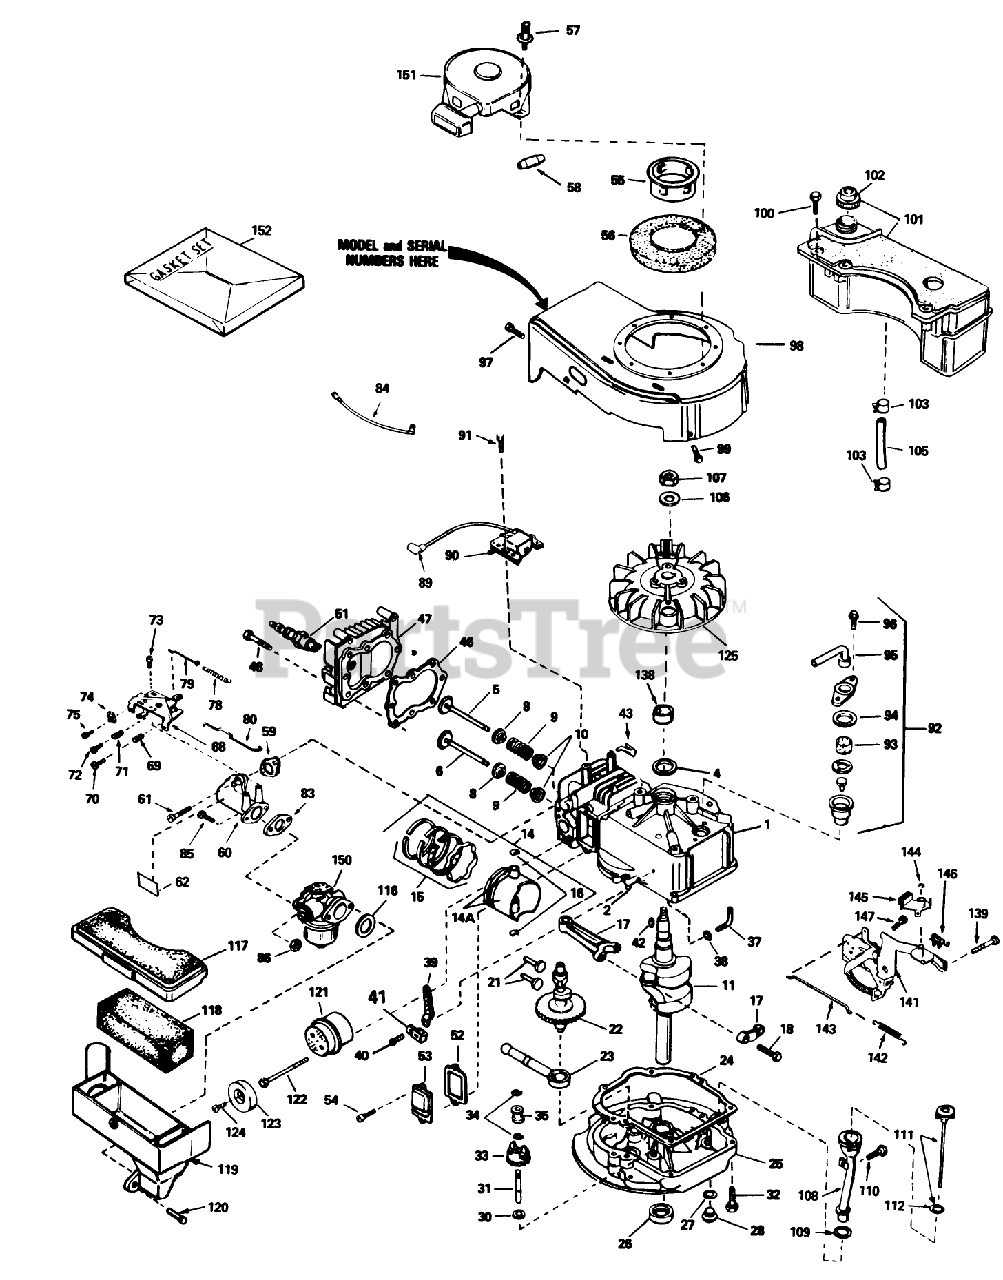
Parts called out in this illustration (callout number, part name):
1	Cylinder Assembly (Incl. Ref. #2, 4, 94 96)
2	Pin-Dowel
4	Seal-Oil
5	Valve, Intake (Std.) (Incl. Ref. #40)
5	Valve, Intake (1/32" oversize)(Incl. No. 40)
6	Valve, Exhaust (Std.)(Incl. No. 40)
6	Valve, Intake (1/32" oversize)(Incl. No. 40)
8	Cap-Upper Valve Spring
9	Spring-Valve
10	Cap-Valve, Spring
11	Crankshaft
14	Piston-Pin Ring Assy. (Std.)(Incl. Ref. #14A, 15 16)
14	Piston-Pin Ring Assy. (.010 oversize)(Incl. Ref. #14A, 15 16)
14	Piston-Pin Ring Assy. (.020 oversize)(Incl. Ref. #14A, 15 16)
14A	Piston Pin Assy. (Std)(Incl. Ref. #16)
14A	Piston Pin Assy. (.010 oversize) (Incl. Ref. #16)
14A	Piston Pin Assy. (.020 oversize) (Incl. Ref. #16)
15	Piston Ring Set Std.
15	Piston Ring Set .010 O.S.
15	Piston Ring Set .020 O.S.
16	Ring-Retaining, Piston Pin
17	Rod Assy., Connecting (Incl. Ref. #17)
18	Bolt-Rod, Connecting
21	Lifter-Valve
22	Camshaft(Mech.Comp. Release)
23	Oil Pump ASM
24	Gasket, Mounting
25	Flange Assy.-Mounting (Incl. Ref. #26, 27, 28 31)
26	Seal Oil
27	Gasket-Oil Drain
28	Plug Oil Drain
30	Washer-Flat
31	Shaft-Governor
32	Screw (1/4-20 x 1-1/4)
33	Governor Gear ASM
34	Ring-Retaining
35	Spool-Governor
37	Rod, Governor (Incl. No. 36)
38	Washer-Flat
39	Governor Lever
40	Screw
41	Clamp-Lever, Governor
42	Key-Flywheel
43	Clip-Wire
46	Gasket-Cylinder Head
47	2025A67 ADD.ASSEMBL
48	Screw (5/16-18x1-1/2)
51	Plug, Spark (Autolite 458, Champion J-19LM or equiv.)
52	Gasket-Breather
53	Cover-Valve
54	Screw
55	Cup-Starter
56	Screen-Starter
57	Pop Rivet (Can be purchased locally)
58	Retainer-Starter Rope
59	Gasket-Intake
60	Pipe-Intake (Incl. Ref. #59)
61	Screw (1/4-20 x 1)
62	Decal-Primer
68	Control Assy.-Remote Speed (Incl. Ref. #69 thru 72 76)
69	61709/GIL1515A/95-5
70	Screw
71	Spring-Compression
72	Screw
73	Screw (10-24 x 9/16)
74	Conduit
75	Screw (10-32 x 3/8)
78	Spring Governor
79	2035A67 ADD.ASSEMBL
80	Link-Throttle
83	Gasket
84	Ground Wire
86	Nut and Lock Washer (1/4-28)
89	Cover-Spark Plug
90	Solid State
91	Screw
92	Breather Assy. (Incl. Ref. #46 thru 51)
93	Element-Breather
94	Gasket-Breather
95	Tube, Breaker
96	Screw (10-24 x 9/16)
97	Screw (10-24 x 9/16)
98	Housing-Blower
99	Screw (1/4-20 x 1/2)
100	Screw (10-32 x 35/64)
101	Tank Assembly-Fuel (Incl. Ref. #102)
102	Cap-Fuel
103	Clamp-Line, Fuel
105	Line-Fuel
106	Washer-Belleville
107	Nut-Flywheel
108	Tube-Oil Fill
109	Gasket
110	Screw (10-32 x 1/2)
111	Dipstick-Oil (Incl. Ref. #112)
112	O-Ring
116	Gasket-Cleaner, Air
117	Cover Air Cleaner
118	Filter-Air Cleaner
119	Body Air cleaner
120	Screw
121	Muffler (Incl. Ref. #122)
122	Screw
123	Cover-Muffler
124	Screw
125	Flywheel
138	Spacer
139	Screw (1/4-20 x 3/8)
141	Bracket Assy.
142	Spring-Extension
143	Link-Control
144	Ring-Retaining
145	Lever-Brake
146	Terminal
147	Screw-Hex. Hd.
150	Carburetor (Incl. Ref. #83)
151	tarter-Rewind
152	Gasket Set
